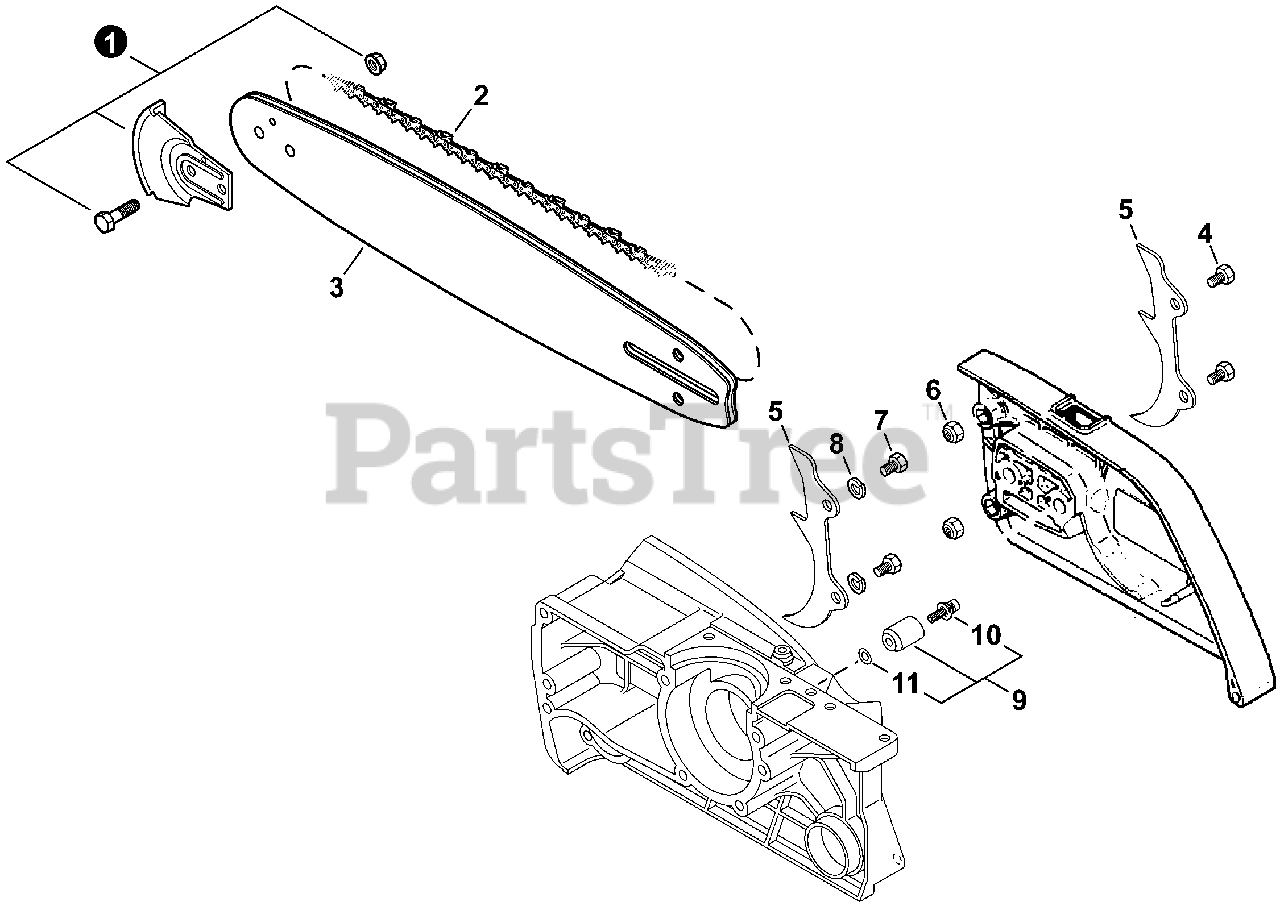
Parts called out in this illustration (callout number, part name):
1	KICK GUARDT KIT
2	SAW CHAIN - 20"
2	SAW CHAIN - 24"
2	SAW CHAIN - 28", 0.050 GAUGE, 3/8" PITCH
2	SAW CHAIN - 32", 0.050 GAUGE, 3/8" PITCH
2	SAW CHAIN - 36"
3	GUIDE BAR, 20"
3	GUIDE BAR, 24"
3	GUIDE BAR, 27"
3	GUIDE BAR, 32"
3	GUIDE BAR, 36"
5	SPIKE, BUMPER
6	NUT, LOCK 6
7	BOLT 6x20
8	WASHER, SPRING 6
9	CHAIN CATCHER KIT
10	BOLT 5x20
11	WASHER, FLAT 5.5x10x0.8
